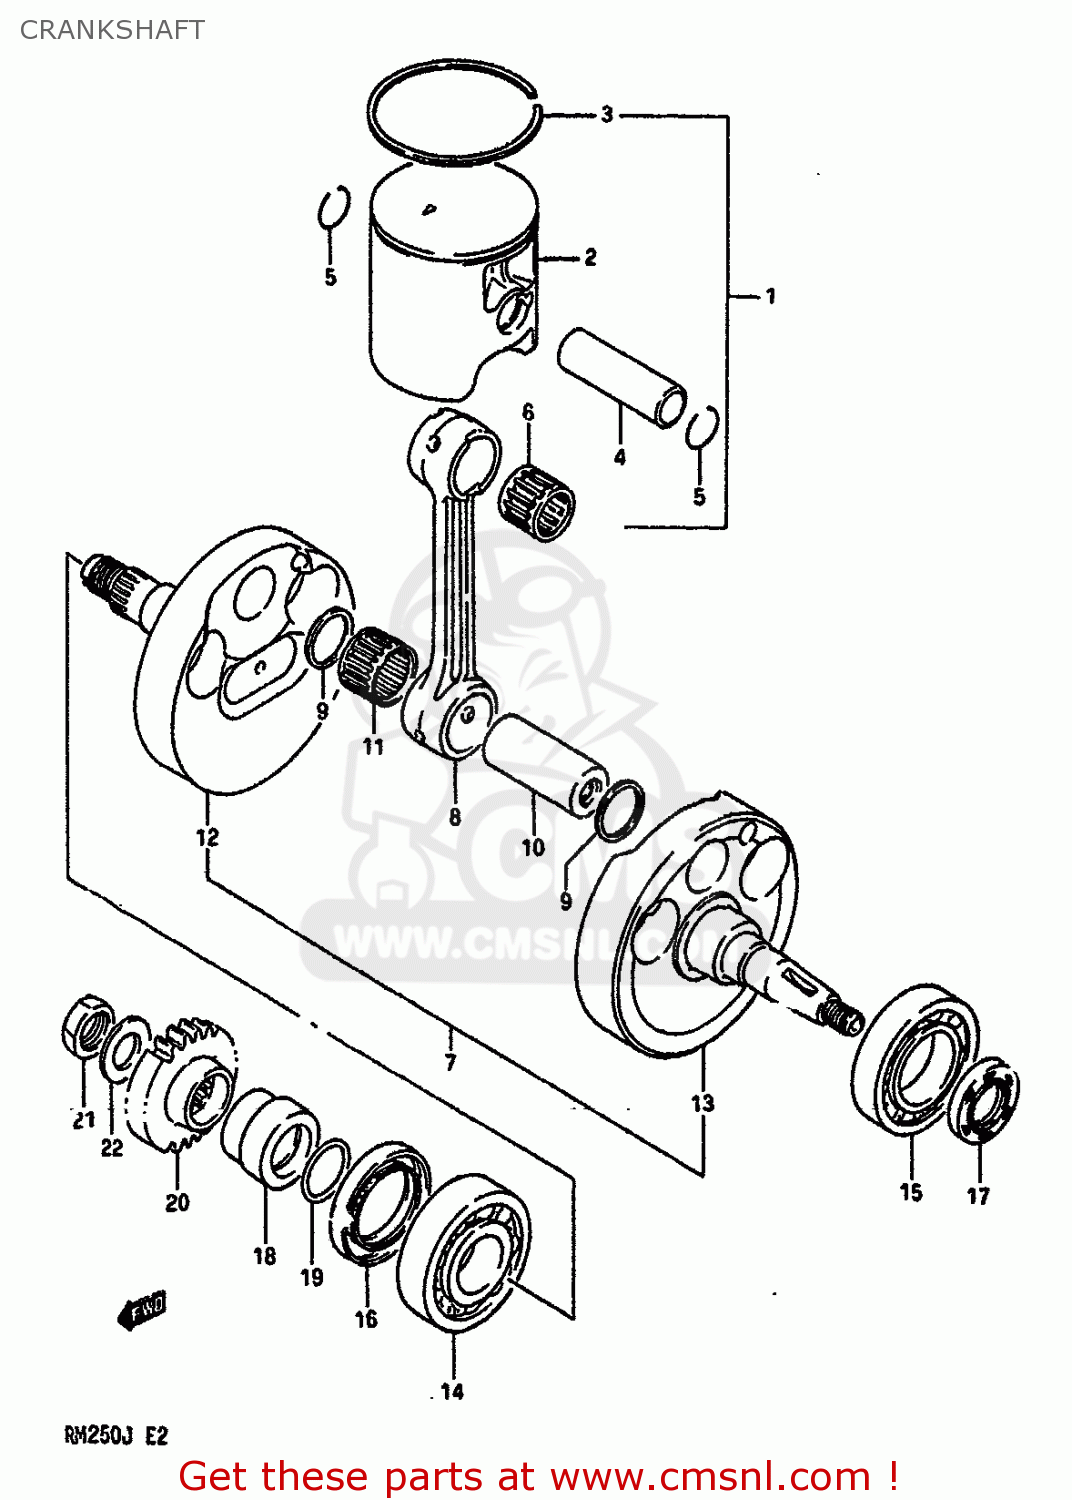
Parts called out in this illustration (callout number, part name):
1	PISTON SET (STD)
2	PISTON (67.00MM)
3	RING,PISTON
4	PIN,PISTON
5	CIRCLIP,PISTON PIN
6	BEARING(18X23X22)
7	CRANKSHAFT ASSEMBLY
8	CONNECTION ROD
9	WASHER(24X29X1.5)
10	PIN COMP,CRANK
11	BEARING
12	CRANKSHAFT,R
13	CRANKSHAFT,LEFT
14	BEARING(25X62X17)
15	BEARING(30X62X16)
16	SEAL,OIL(36X52X8)
17	OIL SEAL
18	SPACER,PRIMARY DRIVE GEAR
19	O RING(D:2.4,ID:21.8)
20	GEAR,PRIMARY DRIVE
21	NUT
22	WASHER
